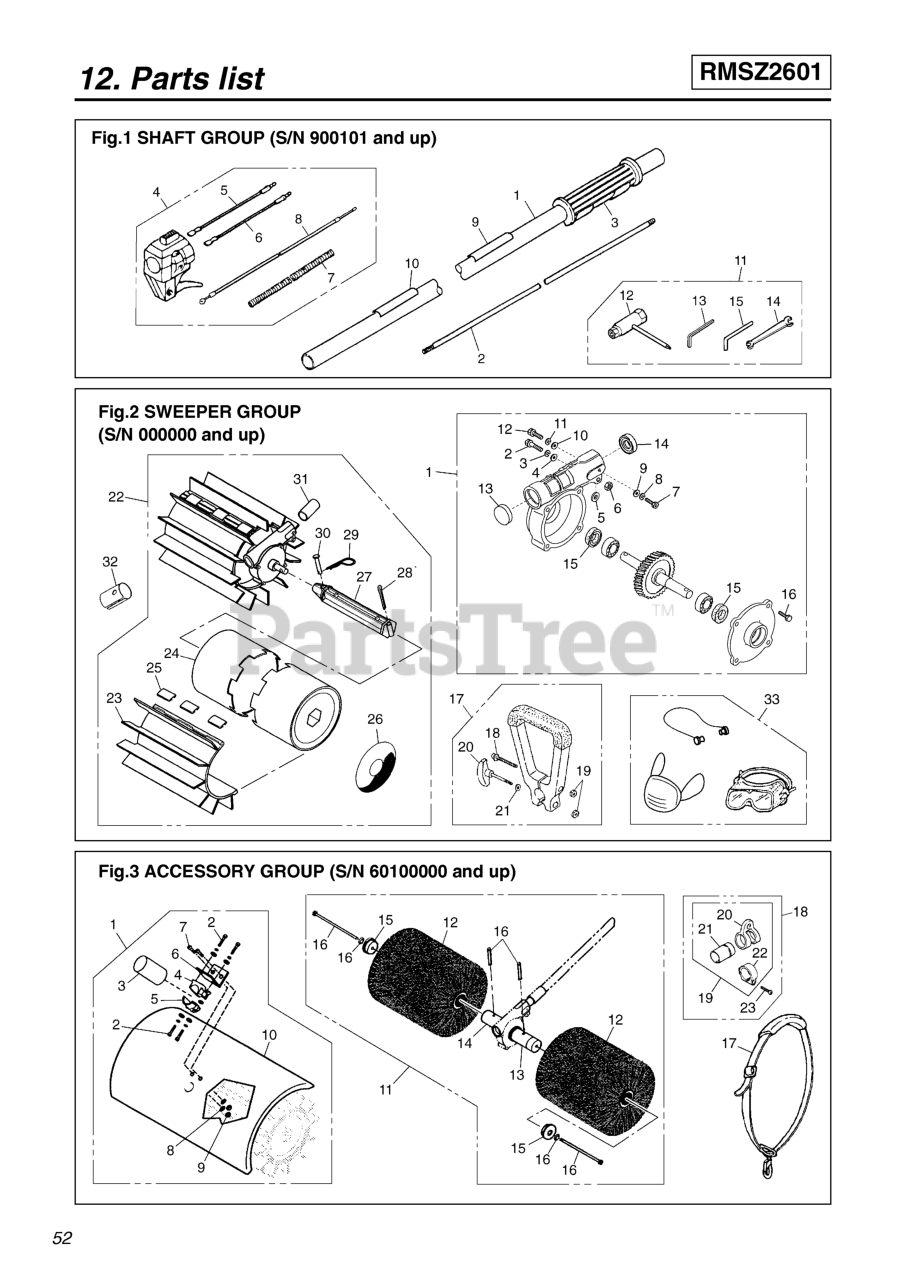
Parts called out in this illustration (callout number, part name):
1	PIPE COMPLETE
3	GRIP (RPLS 3577-32140 & 3220-
5	CORD (A), BLACK
6	CORD (B), RED
7	TUBE (RPLS 4900-72141)
8	CABLE (RPLS 5580-83100)
9	NAMEPLATE
10	PLATE, CAUTION
12	SOCKET
13	WRENCH (TOOL)
14	SPANNER, 8 X 10 (RPLS 2540- )
15	BAR
A2	BOLT, M6 x 30
A3	SPRING WASHER
A4	WASHER, FLAT
A5	WASHER, FLAT
A6	NUT, M6 X 5
A7	BOLT, M5 x 12
A8	WASHER, SPRING M4 x 1.3
A11	WASHER, SPRING M4 x 1.3
A12	SCREW
A13	PLUG, HOUSING
A16	SCREW
A17	HANDLE ASSY (RPLS 99909-33009)
A22	SWEEPER ASSY
A25	CLIP, BELT
A26	LABEL, REDMAX
A27	AXLE, DRUM (RPLS -33016)
A28	PIN, COTTER
A29	PIN, HITCH
A30	PIN, CLEVIS (RPLS -33018)
A31	PROTECTOR, TUBE
A33	SAFETY KIT
B1	DEBRIS SHIELD ASSEMBLY
B4	BRACKET, HANDLE
B5	CAP, LOWER
B6	BRACKET, SHIELD
B11	BRUSH SWEEPING ATTACH (NYLON)
B12	BRUSH, NYLON
B13	ADAPTOR, GEAR SHAFT, LH
B14	ADAPTOR, GEAR SHAFT, RH
B16	KIT, BRUSH HARDWARE
B18	HANGER ASSEMBLY
B19	HANGER COMPLETE
B20	HANGER
B21	CLAMP
B22	SLEEVE
B23	SCREW, M5 x 25
